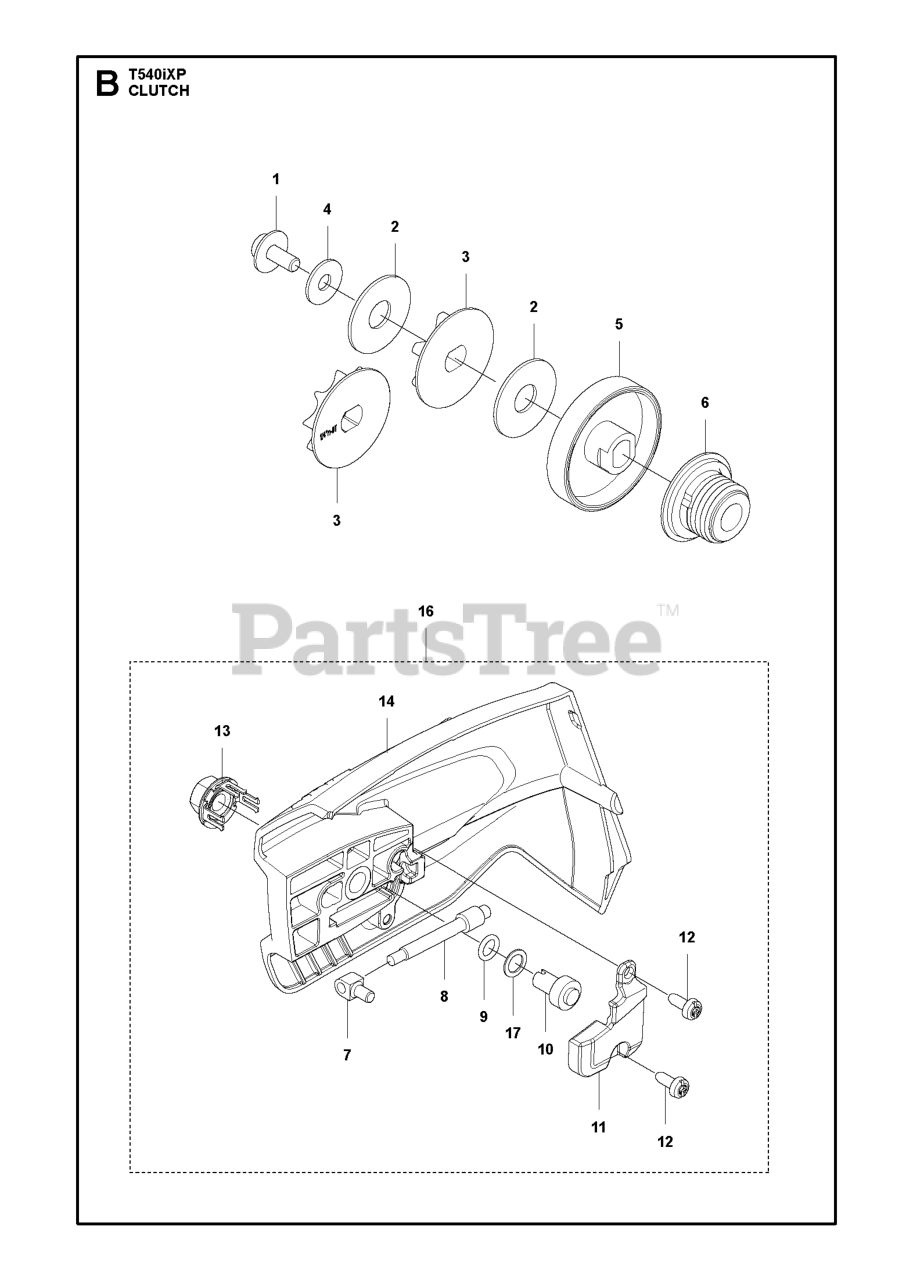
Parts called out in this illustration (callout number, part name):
1	SCREW
3	Sprockets
3	SPUR SPROCKET 1/4IN MINI 9T SP
4	WASHER 5.3X15
7	PIN BAR ADJUSTING
10	WORM WHEEL LEFT HAND TEETH
11	COVER LID
13	NUT RETAINER ASSY
14	CLUTCH COVER T540I XP
16	CLUTCH COVER
